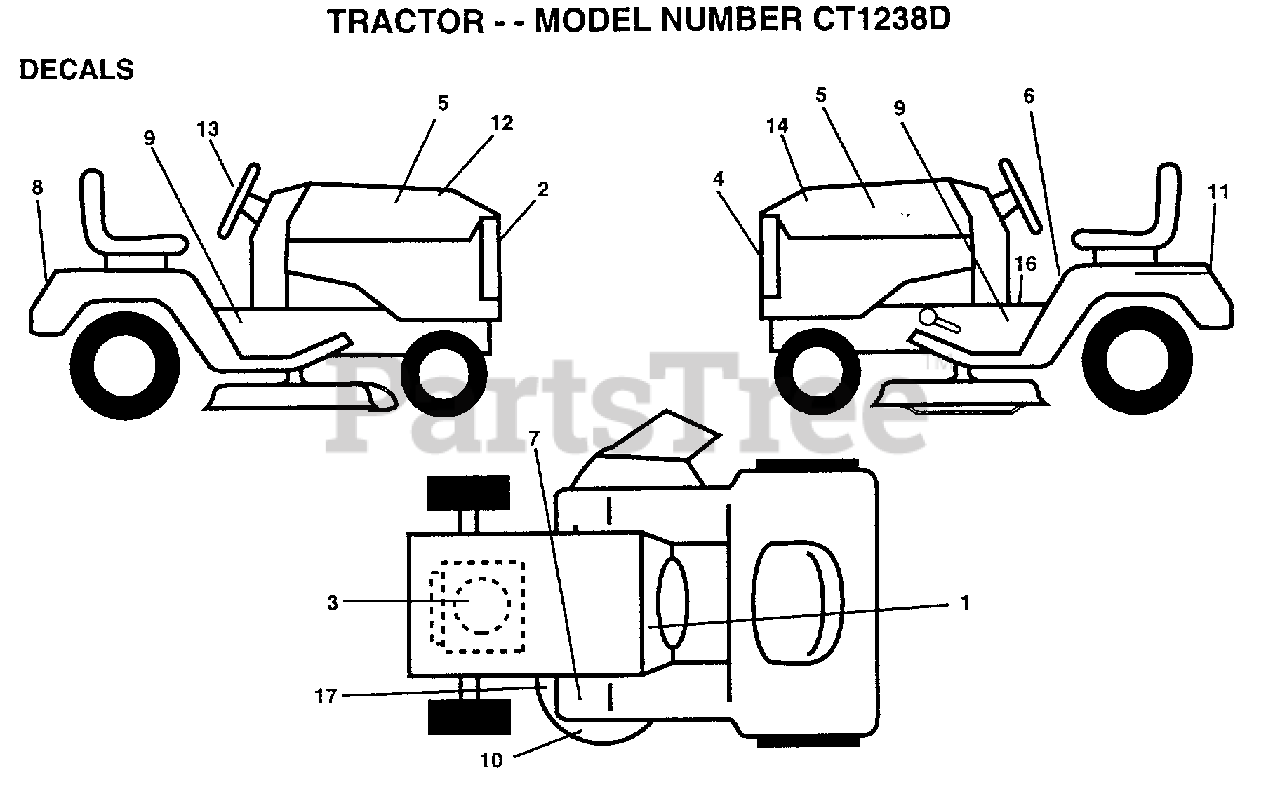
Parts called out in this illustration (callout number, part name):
1	DECAL.DASH.INST.
2	GRILL DECAL
3	DECAL, HP ENGINE
5	DECAL.HOOD.INS.
6	DECAL
8	FENDER DECAL
9	DECAL CHASSIS SPEED DECK
11	DECAL.BTRY.DANGER
12	DECAL HOOD RH RLY
13	"DECAL,STR WHL"
14	DECAL HOOD LH RLY
16	DECAL BRAK PARK
17	DECAL
